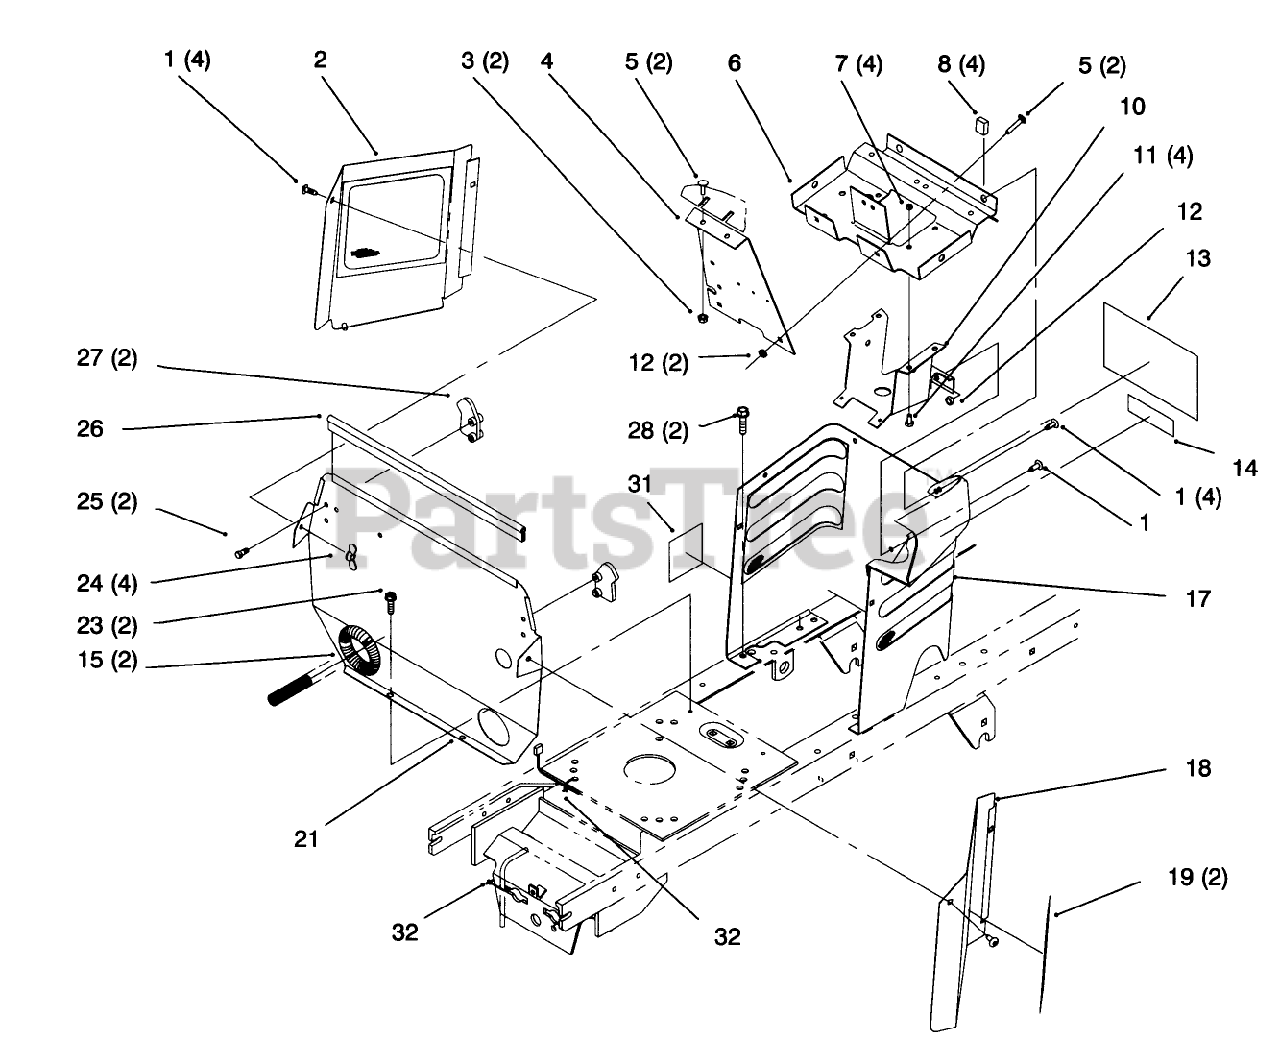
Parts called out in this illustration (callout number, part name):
1	SCREW-HH
2	RH SIDE COVER ASM
3	NUT-KEPS
5	SCREW-CARR
6	SUPPORT-DASH
7	NUT-HEX
8	NUT RETAINER - J TYPE
10	BRACKET-COLUMN, LOWER
11	SCREW-HH
12	NUT-LOCK, NI
13	DECAL - DANGER
13	DECAL-DANGER
14	DECAL-INSTRUCTION
15	COVER-SHAFT, DRIVE
17	HOODSTAND W/DECALS
18	LH COVER ASM
19	DECAL, 264-G
19	DECAL - 264-H
19	Decal-268-H (Only On: 72103)
21	FIREWALL
23	SCREW-HWH
24	NUT-WING
25	SCREW-PLASTITE
26	TRIM-SEAL, FIREWALL
27	LATCH-HOOD
28	SCREW-HWHTF
32	TIE-CABLE
